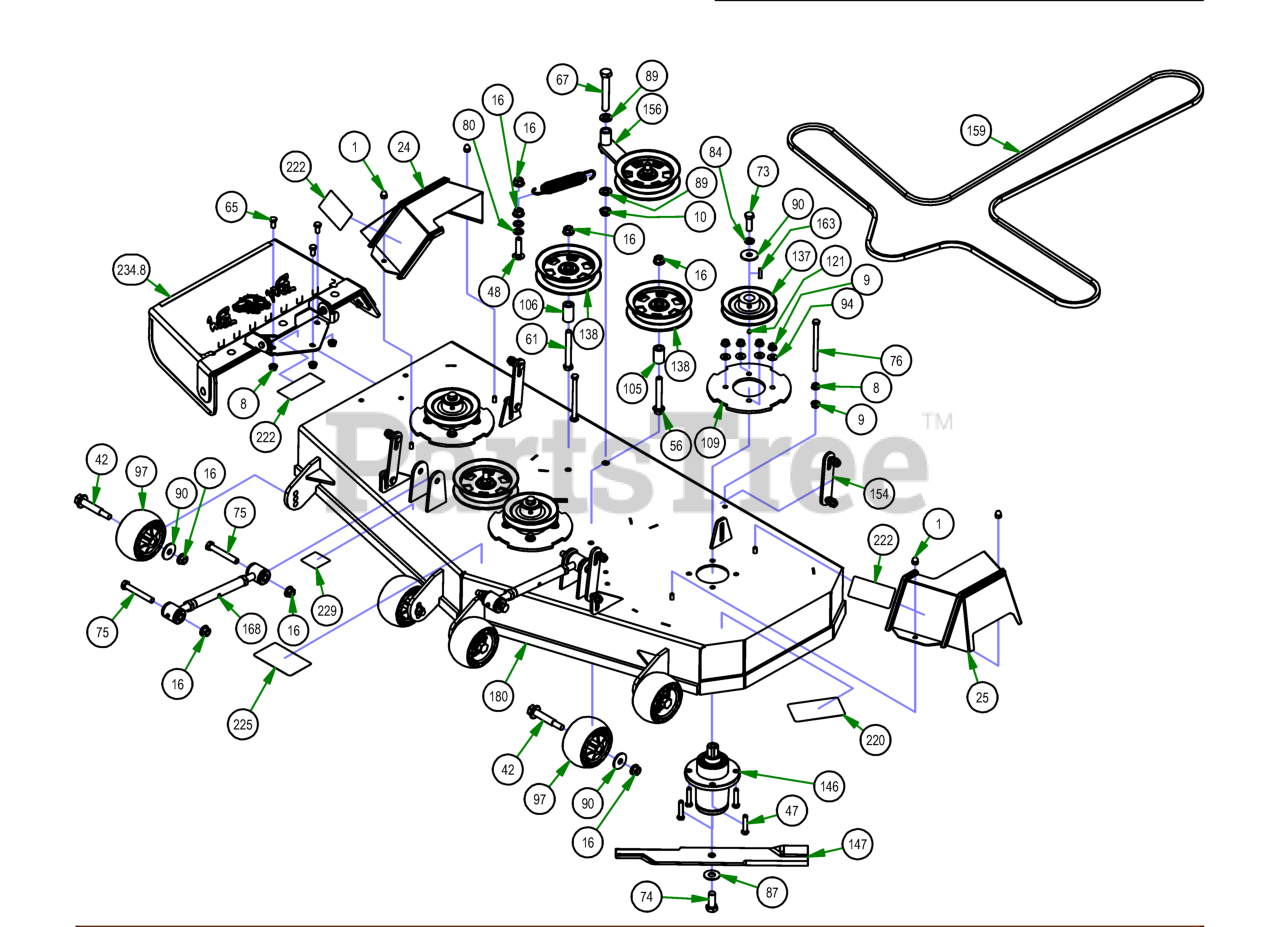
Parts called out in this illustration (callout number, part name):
1	5/16-18 ACORN NUT HIGH-CROWN ZC
8	3/8-16 HEX SERRATED FLANGE NUT HARD/ZINC
9	3/8-16 NYLON INSERT FLANGE LOCKNUT (GR.F) ZINC
10	5/8-11 NYLON INSERT JAM LOCKNUT ZINC
16	1/2-13 NYLON INSERT FLANGE LOCKNUT ZINC
24	2021 Maverick 54”/60” RH Pulley Cover
25	2021 Maverick 54”/60” LH Pulley Cover
42	Deck Wheel Bolt
47	3/8-16 X 1-3/4 HEX C/S (GR.5) ZC
48	1/2-13 X 2 CARRIAGE BOLT ZINC
56	1/2-13 X 3-1/2 HEX FLANGE BOLT (GR.8) ZINC
61	1/2-13 X 4 HEX CAP SCREW (GR.8) ZINC YELLOW
65	3/8-16 X 3/4 HEX CAP SCREW (GR.5) ZINC
67	5/8-11 X 4 HEX CAP SCREW (GR.8) ZINC YELLOW
73	1/2-20 X 1-1/2 HEX CAP SCREW (GR.5) ZINC
74	5/8-18 X 1-1/2 HEX CAP SCREW (GR.8) ZINC YELLOW
75	1/2-13 X 3-1/2 HEX CAP SCREW (GR.5) ZINC
76	3/8-16 X 5-1/2 HEX CAP SCREW (GR.5) ZINC
80	.517 SQ WDTH ID X .937 OD X .060 THICK F/W PHOS/OIL
84	1/2 SPLIT LOCKWASHER (GR.8) ZINC/YELLOW
87	5/8 USS FLAT WASHER (1-3/4" OD) GR.8 ZINC YELLOW
89	.635 ID X 1.120 OD X .140 THICK FLAT WASHER NYLON
90	1/2 BELLEVILLE WASHER (1-5/8 OD X .140 THK) ZINC
94	5/16 USS FLAT WASHER (7/8 OD) ZINC
97	Deck Wheel
105	.502 ID X .750 OD X 1.500 Long Spacer
106	1 3/4" Pulley Spacer
109	Deck Spindle Support Plate
121	5/16-24 X 1/4 SOCKET SET SCREW (CUP PT) PLAIN
137	5.25" Deck Spindle Pulley
138	5-3/4 Idler Pulley
141	Deck Idler Spring
146	Spindle Assembly
147	54" Fusion Blade for ZT/Mav/Outlaw/Revolt
154	Deck Hanger Assembly
156	2017 MZ/ZT Deck Idler Assembly
159	B155.75 Deck Belt
163	1/4 X 1 SQ MACHINERY KEY 1018 STL PLN
168	2018 Maverick Turnbuckle (Top Link)
180	54 ZT Welded Deck
220	2018 54" Deck Decal
222	Danger Decal-Spindle/Discharge
225	Deck Belt Route Decal
229	Deck Impact Patent Decal 9591803
234	Discharge Chute Assembly
